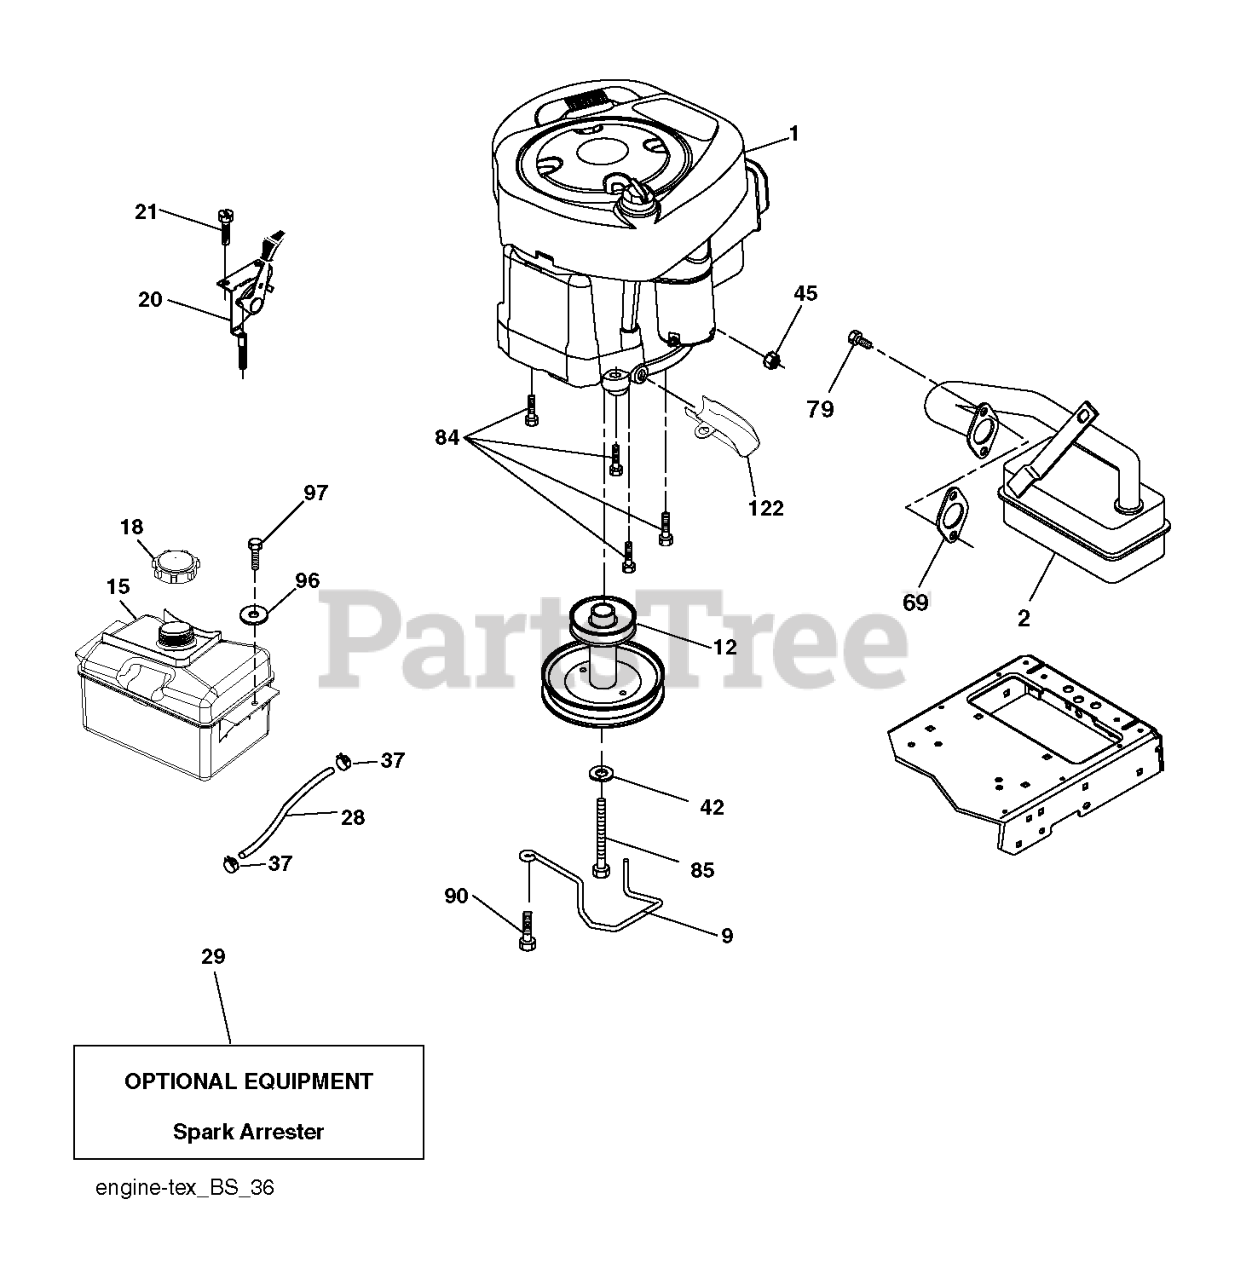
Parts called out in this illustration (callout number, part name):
2	MUFFLER.B&S.MODEL.21.11HP.OHV
9	KEEPER.BELT.ENGINE.3.25 (3 2)
12	PULLEY.ENG.CL.MECH.SLVR.LT/YT
15	FUEL.TANK.ASM.NON-EPA
18	CAP ASM.FUEL.2.25"FR.
20	CONTROL.TH/CK.C.
21	SCREW.#10 X 0.750.BOS
28	LINE.FUEL.20
29	KIT.SPARK ARRESTOR 794945 B&S
37	HOSE CLAMP
42	LOCKWASHER
45	NUT
69	REPL BY 532 27 22-93
79	SCREW.SOCKET HD.5/16-1
84	SCREW.3/8-16
85	BOLT HEX 7/16-20X4-1/4"
90	SCREW 3/8-16X1
96	WASHER
97	SCREW HEXWSHR 1/4-20X3/4
122	EXTENSION DRAIN OIL
